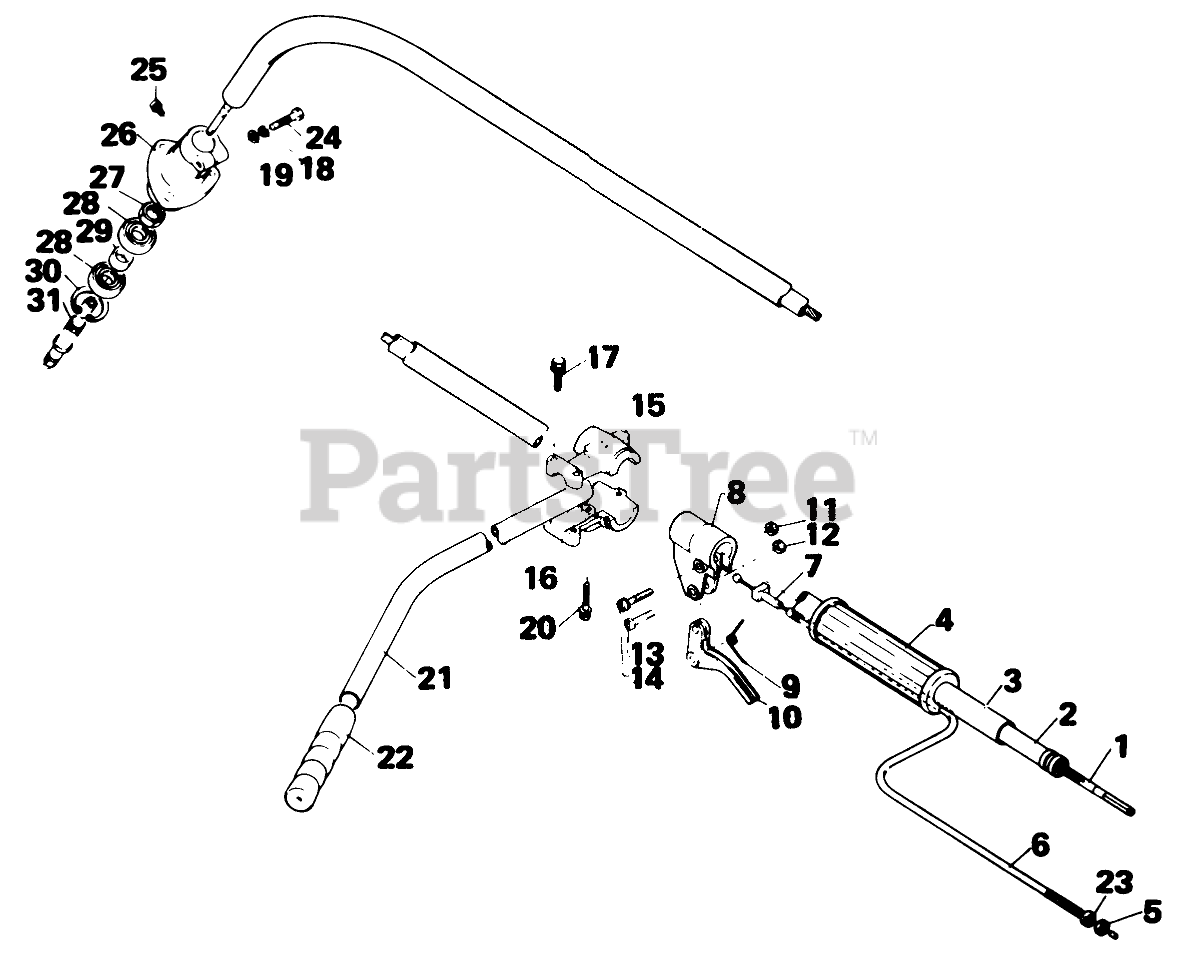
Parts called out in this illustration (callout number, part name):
1	Shaft, Driving
2	Bushing
3	Housing, Driving Shaft
6	Throttle Cable
7	SPACER
8	Bracket, Throttle Trigger
9	Spring Return
10	Throttle Trigger
11	Nut
13	Screw
14	Screw
15	Bracket, Handle
16	Bracket, Handle
18	Washer
19	Washer
21	Handle
23	Nut, Special
24	SCREW
25	SCREW
26	Housing, Bearing
28	Bearing
29	Spacer
30	Circlip
31	Shaft, P.T.O.
